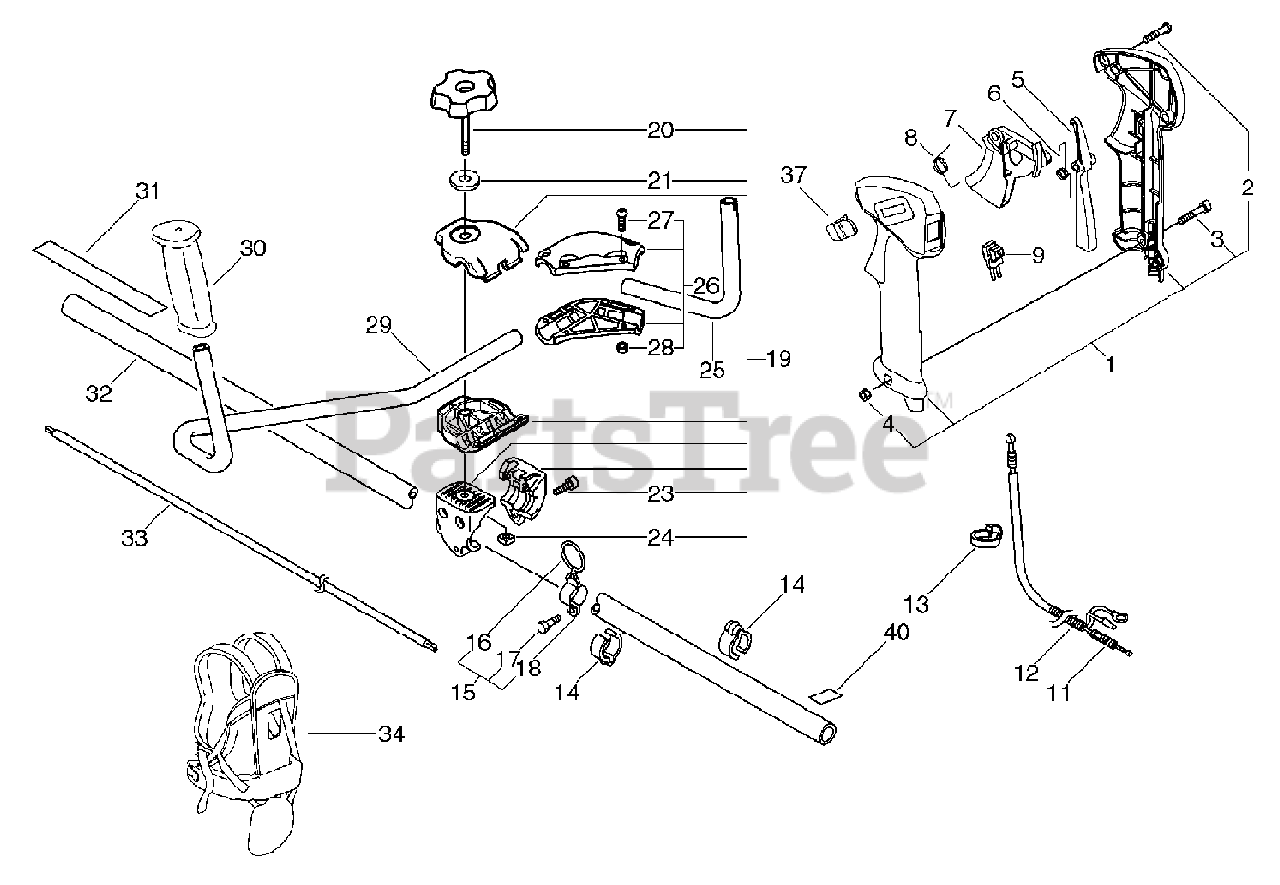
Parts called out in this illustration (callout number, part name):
1	HANDLE GRIP ASSY - FRONT
1	CONTROL HANDLE ASSY
2	SCREW - 3X25
2	SCREW - 4X16
3	SCREW - 5X30
5	LOCKOUT, THROTTLE
5	LEVER, TRIGGER LOCKOUT
6	SPRING, LOCKOUT LEVER
6	SPRING
7	TRIGGER, THROTTLE
8	SPRING, TRIGGER
9	SWITCH, IGNITION
11	CABLE, THROTTLE
12	TUBE
13	CLIP
15	HANGER KIT
17	SCREW - 5X12
18	CLAMP
19	HANDLE BRACKET ASSY
19	HANDLE BRACKET KIT
20	BOLT - 8X55
20	THUMBSCREW
21	WASHER - 8
22	SCREW - 5X20
23	SCREW - 5X30
26	HANDLE BRACKET ASSY
26	HANDLE BRACKET KIT
27	SCREW - 5X20
29	HANDLE - FRONT
30	GRIP, HANDLE
31	LABEL - CAUTION
32	PIPE, MAIN
33	DRIVESHAFT
34	SHOULDER HARNESS ASSY
34	HARNESS ASSY
35	LABEL - STOP
40	LABEL - ALIGNMENT
